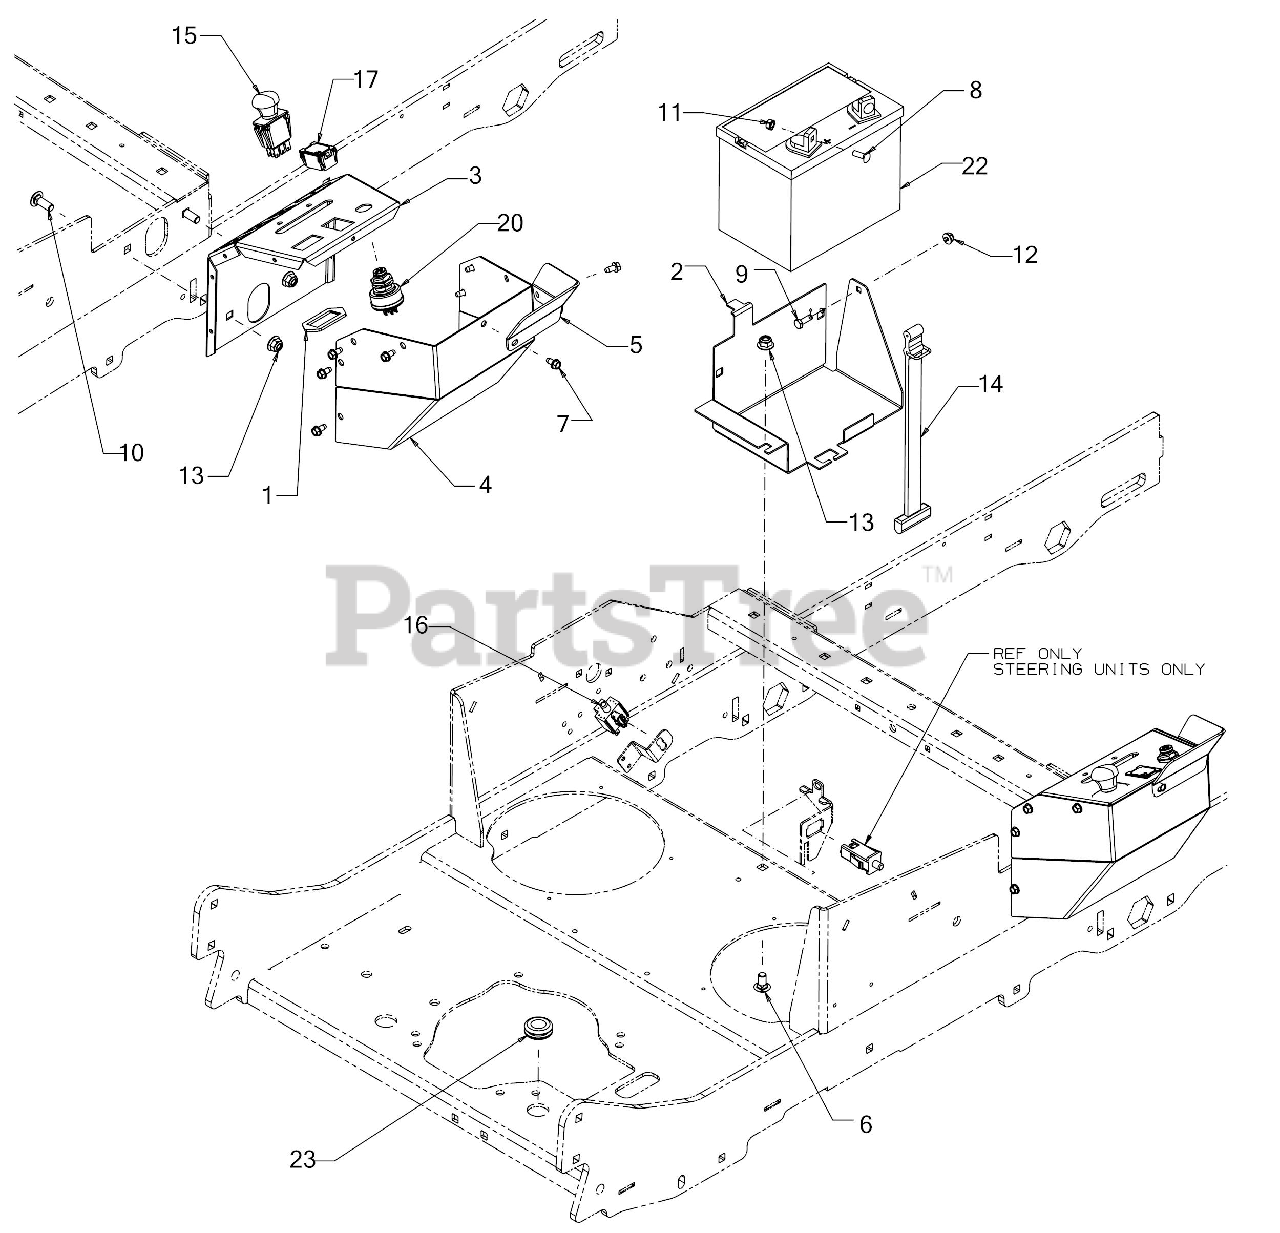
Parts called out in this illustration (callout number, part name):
1	BRACKET-PTO SWITCH
2	BATTERY MOUNTING BRACKET
3	CONTROL POD - (RH)
4	CONTROL POD COVER (RH)
5	THROTTLE DEFLECTOR
6	CARRIAGE BOLT 3/8-16 x .750 GR5
7	SCREW 1/4-20 X.500
8	SCREW 1/4-20 x .75 GR5
9	SCREW 1/4-20X.75 GR5
10	CARRIAGE BOLT 3/8-16 x 1.00 GR5
11	SEMS NUT 1/4-20
12	FLANGE LOCK NUT
14	BATTERY RETAINER STRAP
15	ELECTRIC PTO SWITCH
16	3 POLE SWITCH ( NC-NO-NO)
20	KEY SWITCH (3 POSITION)
23	RUBBER GROMMET
